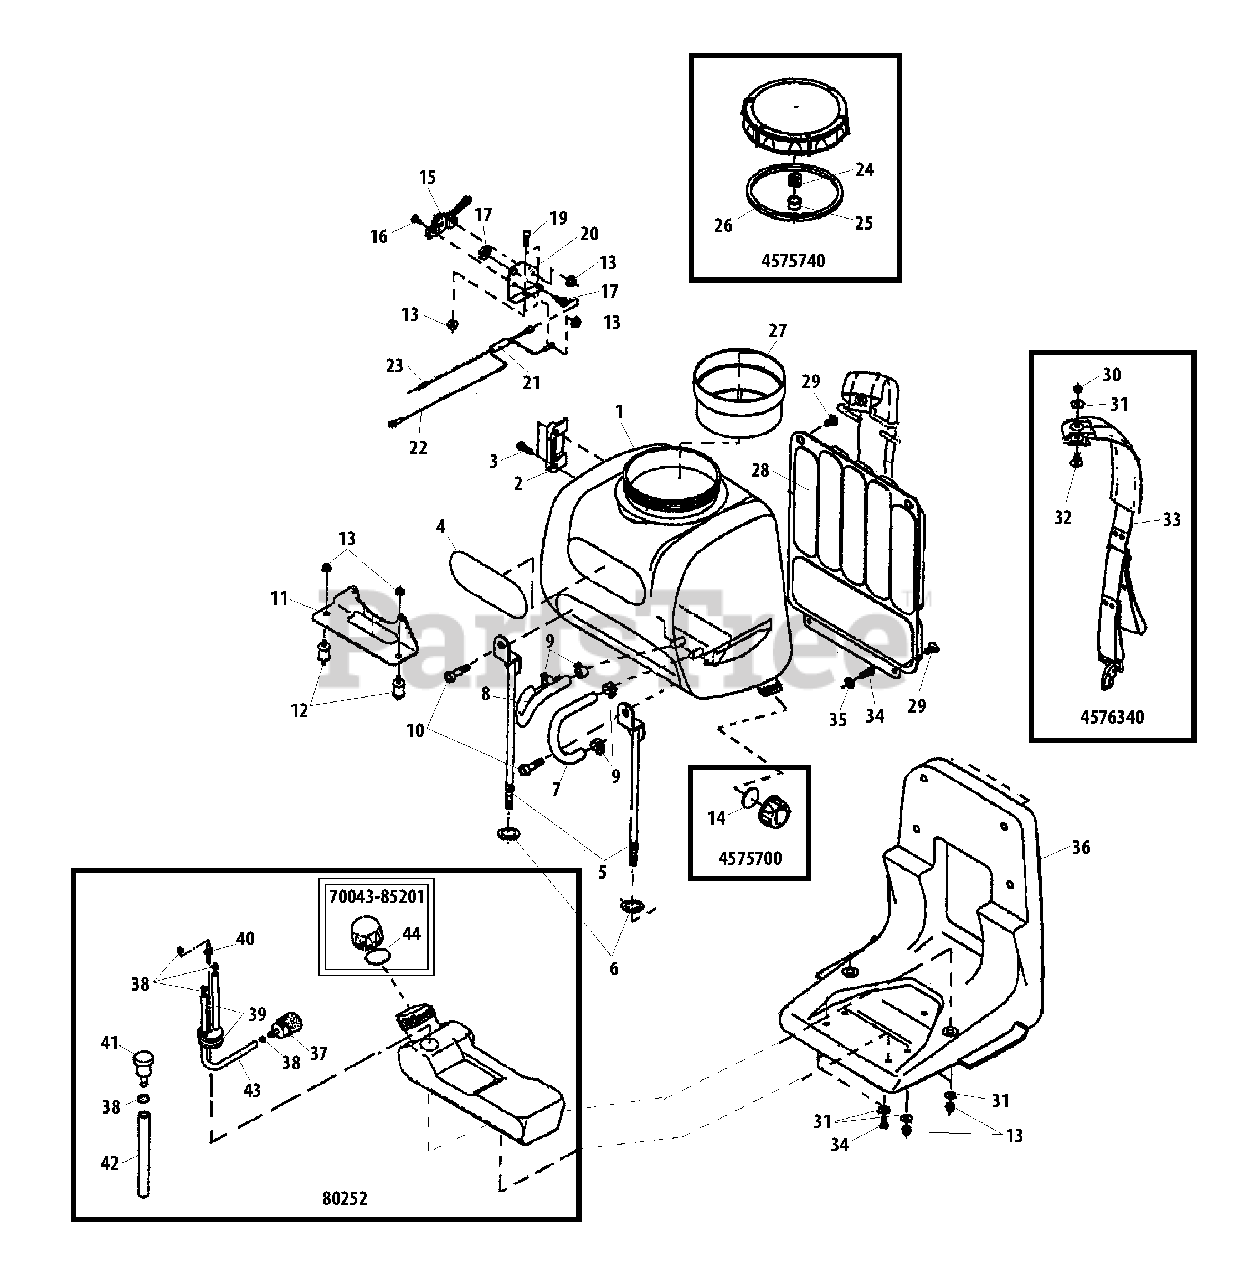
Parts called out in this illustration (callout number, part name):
2	HOLDER, NOZZLE
3	SCREW
4	LABEL - MODEL
5	TANK SUPPORT
6	WASHER
7	TUBE (A)
8	TUBE (B)
9	CLAMP
11	SUBFRAME
12	CUSHION
14	GASKET
15	THROTTLE CONTROL ASSY
16	SCREW
17	SWITCH
19	SCREW
20	PLATE
21	TUBE
22	LEAD - GROUND
24	BREATHER
25	HOLDER
26	O-RING
27	STRAINER, DEBRIS
30	NUT
31	WASHER
32	SCREW
33	STRAP ASSY
34	SCREW
35	WASHER
36	FRAME
37	FILTER, FUEL
38	RING, RETAINING - 6
39	GROMMET
40	CONNECTOR, PIPE
41	VENT, FUEL TANK
42	TUBE
43	PIPE - FUEL
44	GASKET, CAP
70043-85201	CAP ASSY
80252	FUEL TANK ASSY
4575700	DRAIN CAP ASSY
4575740	TANK CAP ASSY
4576340	STRAP ASSY
